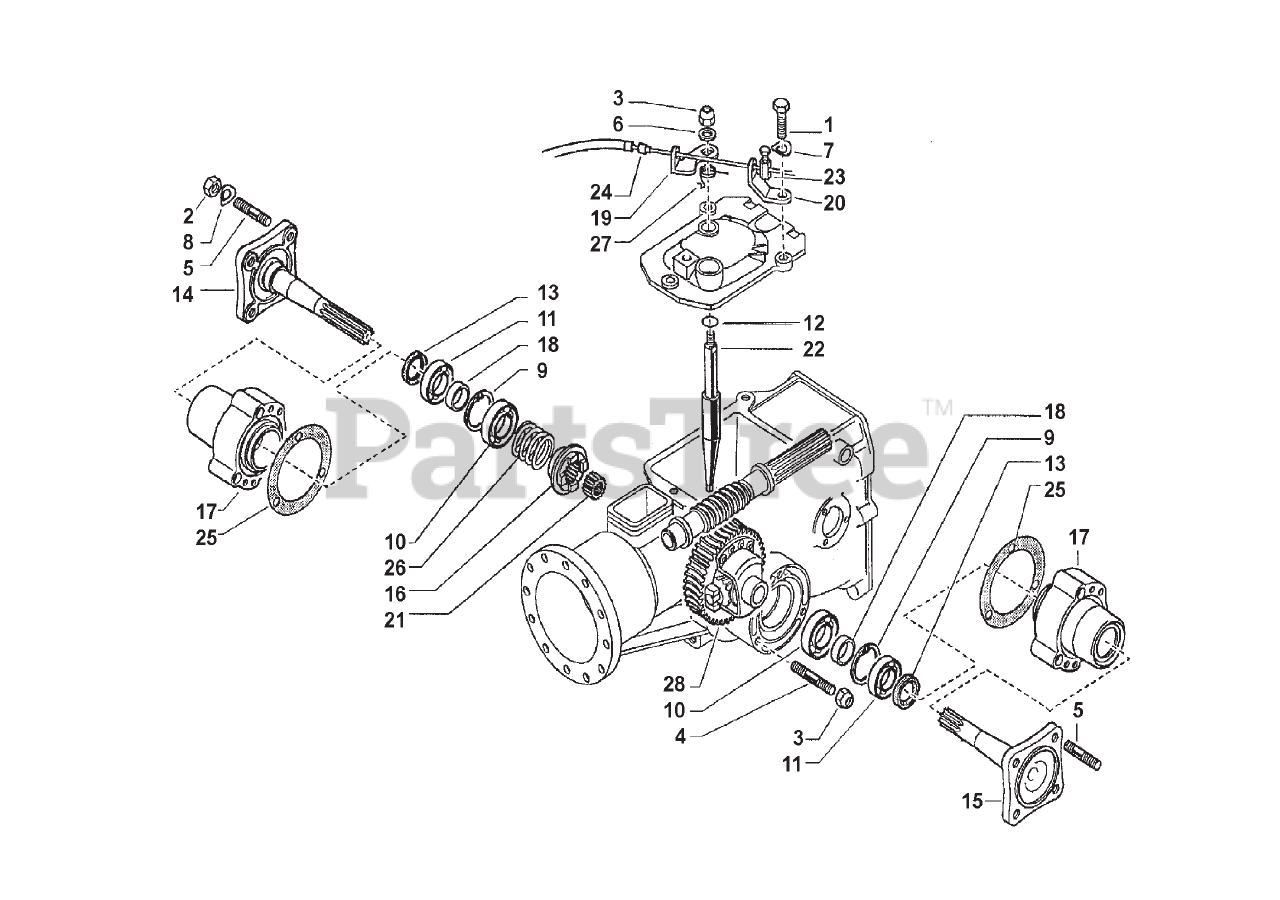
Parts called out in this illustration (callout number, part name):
1	BOLT M8X30
2	NUT M10
3	SELF LOCKING NUT M8
4	STUD M8X46
5	STUD M10X40
6	FLAT WASHER
7	LOCK WASHER
8	WASHER
9	INTERNAL SNAP RING D 47
10	BEARING 20X52X15
11	BEARING 25X47X12
12	O-RING
13	SEAL M30X40X7
14	HALF AXLE RH
15	HALF AXLE LH
16	COUPLING
17	HUB FOR HALF AXLE
19	RELEASE LEVER
20	CABLE BRACKET DIFFERENTIAL
21	DIFFERENTIAL SPACER
23	CABLE CLAMP
24	SHEATH ENDS
25	GASKET
26	SPRING
27	SPRING
28	DIFFERENTIAL COMPLETE
